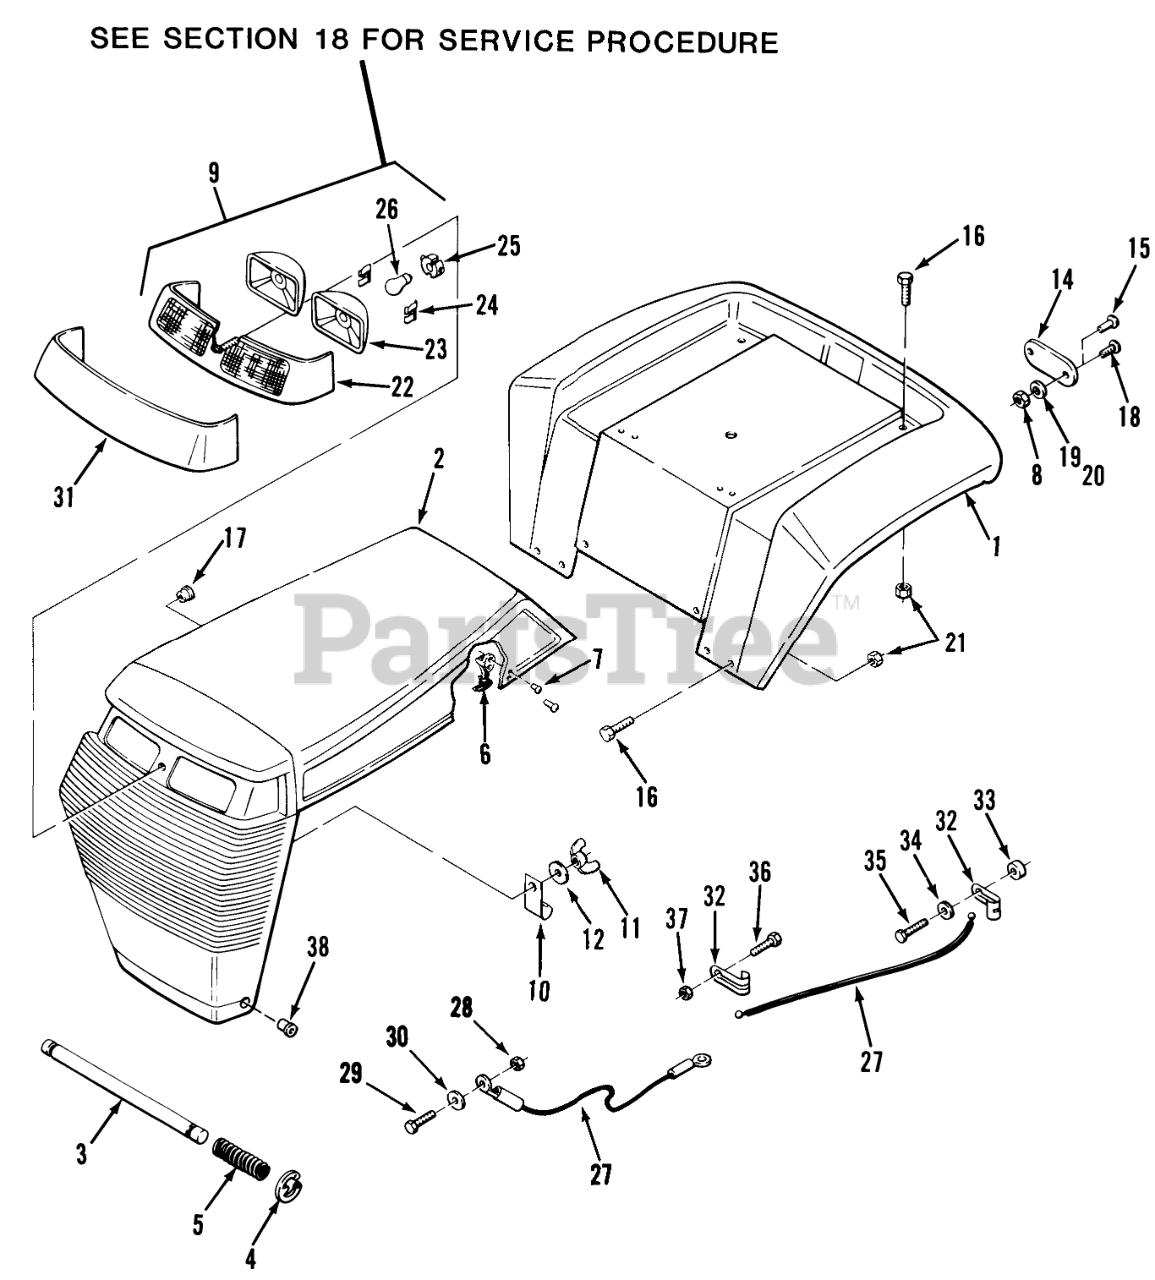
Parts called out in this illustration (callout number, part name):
1	FENDER *R
5	SPRING
6	ASSY-FLEX DRAW LATCH
10	J-CLIP
12	WASHER
17	BUSHING-NYLON 1.093
19	WASHER
23	LIGHT POD
24	RETAINER
26	BULB
27	CABLE-ASS'Y
33	SPACER
38	NYLINER BUSHING
